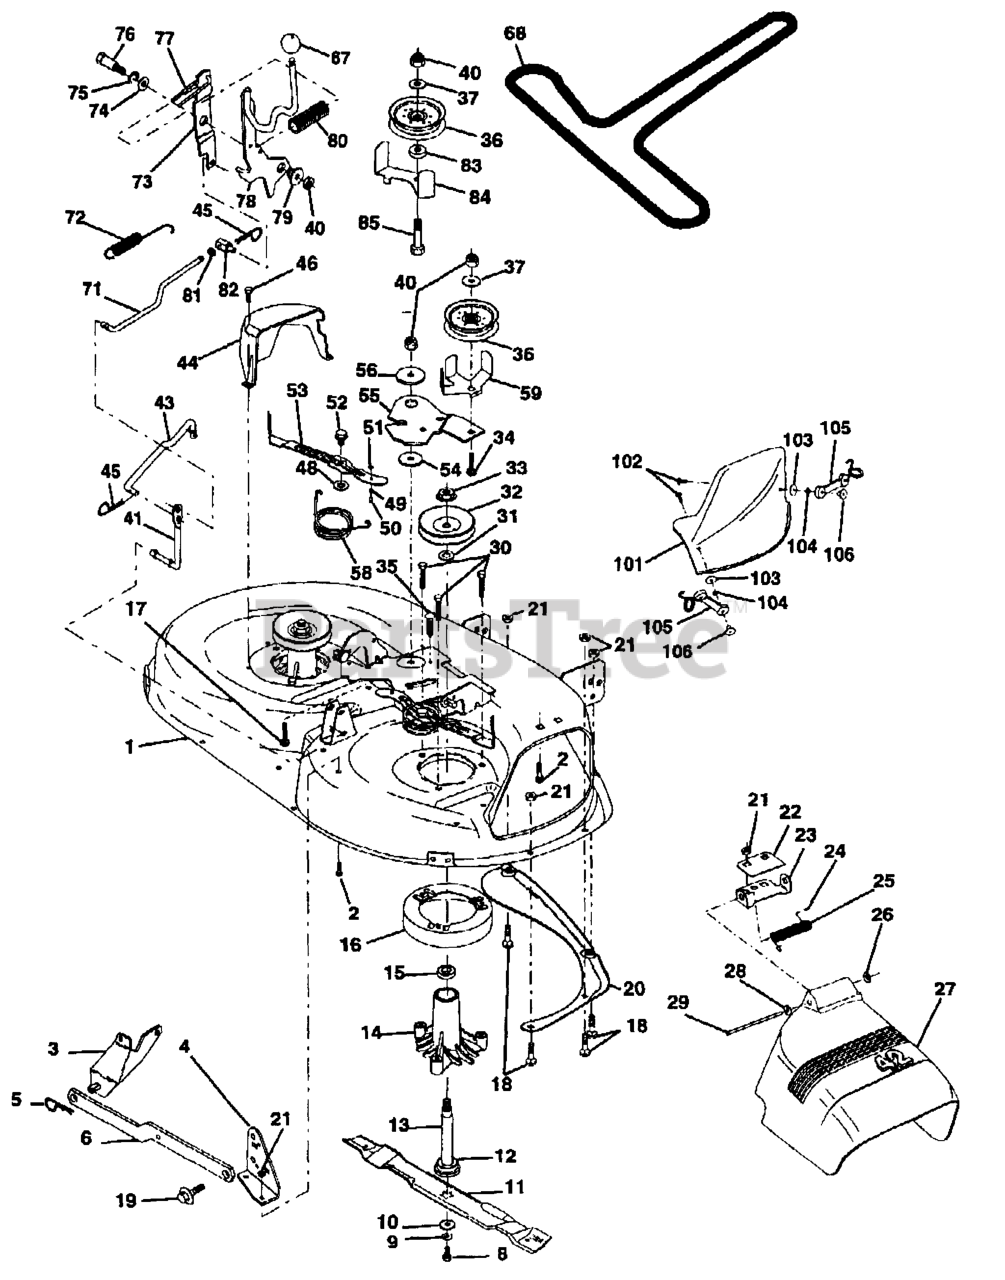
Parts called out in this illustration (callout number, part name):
1	DECK 42"
2	RP BOLT 5/16-18 X3/4 ZN/YEL GR
3	BRKT ASM SWAY BAR
4	BRKT DECK SW BAR
5	RETAINER-SPRNG RB
6	REAR SUSP ARM
8	BLADE BOLT
9	LOCKWASHER
10	WASHER.BLADE
11	BLADE.42".MULCH
12	BEARING.BALL.#6204.(MANDREL)
13	SHAFT ASM VENT
14	HOUSING.MANDREL.VENTED (MACHD)
16	STRIPPER
17	BOLT
18	BOLT
19	BOLT SHD 5/16-18
20	BAFFLE
21	LOCKNUT
22	STIFFENER BRACKET
23	DEFLECTOR BRACKET
24	CAP-SLEEVE LT
25	SPRING TORSION
26	NUT PUSH M
27	SHIELD.DEFLECTOR.MOWER.42".BLK
28	Washer 11/32 X 5/8 X 16 Ga
29	ROD.HINGE
30	SCREW
31	WASHER
32	MANDREL PULLEY
33	NUT
35	FASTENER.XMAS.TREE
36	FLAT IDLER PULLEY
37	WASHER
43	CLUTCH ROD
44	GUARD MANDREL LH BLACK
45	RETAINER M
46	SCREW.1/4-20X5/8
49	CAM FOLLOWER
52	BOLT.SHOULDER.5/16-18
53	ARM
54	HARDENED WASHER
55	IDLER ARM
56	SPACER RETAINER
59	GUARD, BELT
67	KNOB T (1/2-HOLE)
68	V-BELT TRIPATH
71	CLUTCH ROD
72	RETURN SPRING
73	ARM CLUTCH SECONDARY
77	KEEPER SPRING
78	CLUTCH ARM
79	BUSHING.FLANGE.E-RING.GROOVE
80	SPRING
81	NUT
82	TRUNNION.ADJUSTABLE.3/8-16
84	KEEPER BELT
85	BOLT
101	COVER MULCH 42"
102	SCREW
103	LOCKWASHER #10
105	LATCH ASSEMBLY
106	WELDNUT
